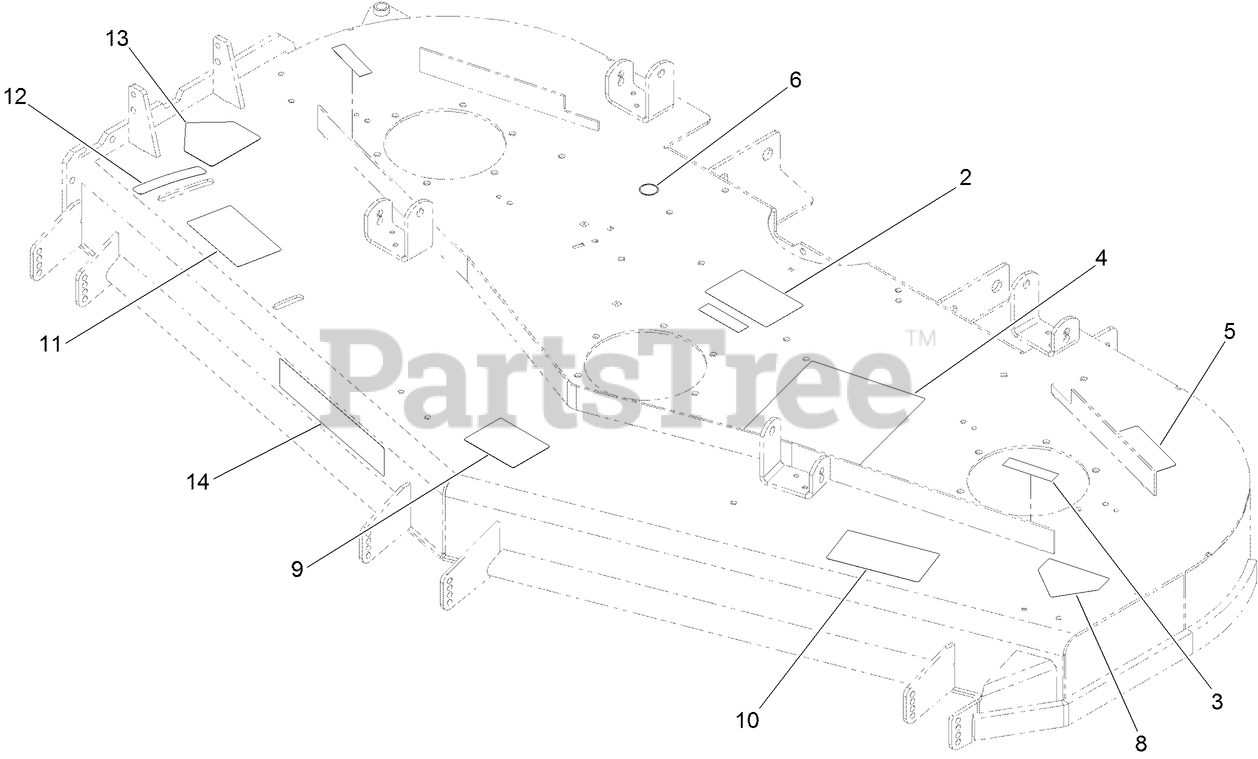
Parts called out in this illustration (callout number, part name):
2	DECAL-ROUTING, BELT
3	DECAL-COVER, MISSING
4	DECAL-CHECK, SERVICE
5	DECAL-TORQUE
6	DECAL-GREASE
8	DECAL-DANGER
9	DECAL-SCALP, ANTI
10	DECAL-DANGER, THROWN OBJECT
11	DECAL-ADJUSTMENT, BAFFLE
12	DECAL-SETTING, BAFFLE
